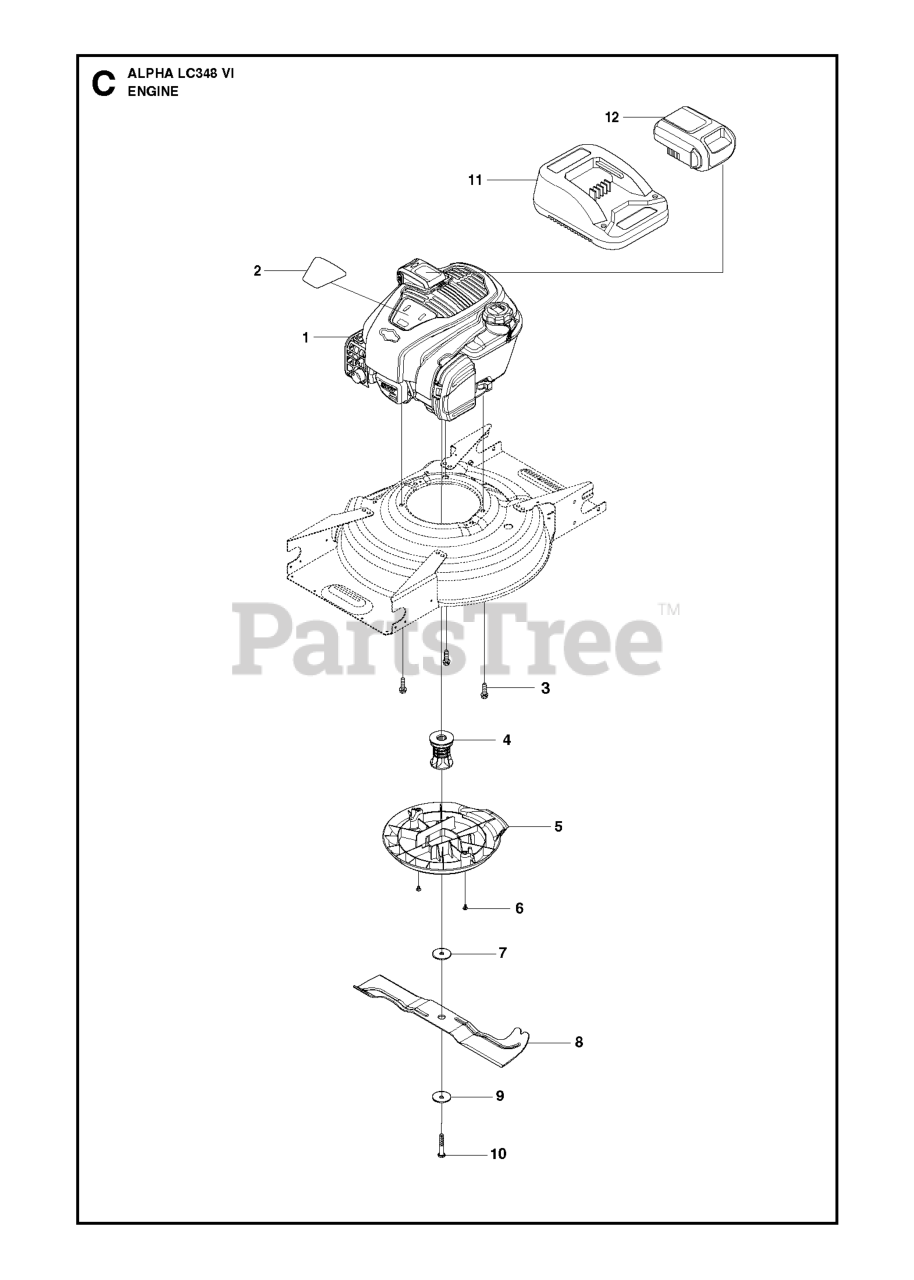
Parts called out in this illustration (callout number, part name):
3	BOLT 3/8-16X1-1/8
5	BELT COVER A009-2
6	SCREW ITXPANTT M5X10 ZPB (A00
